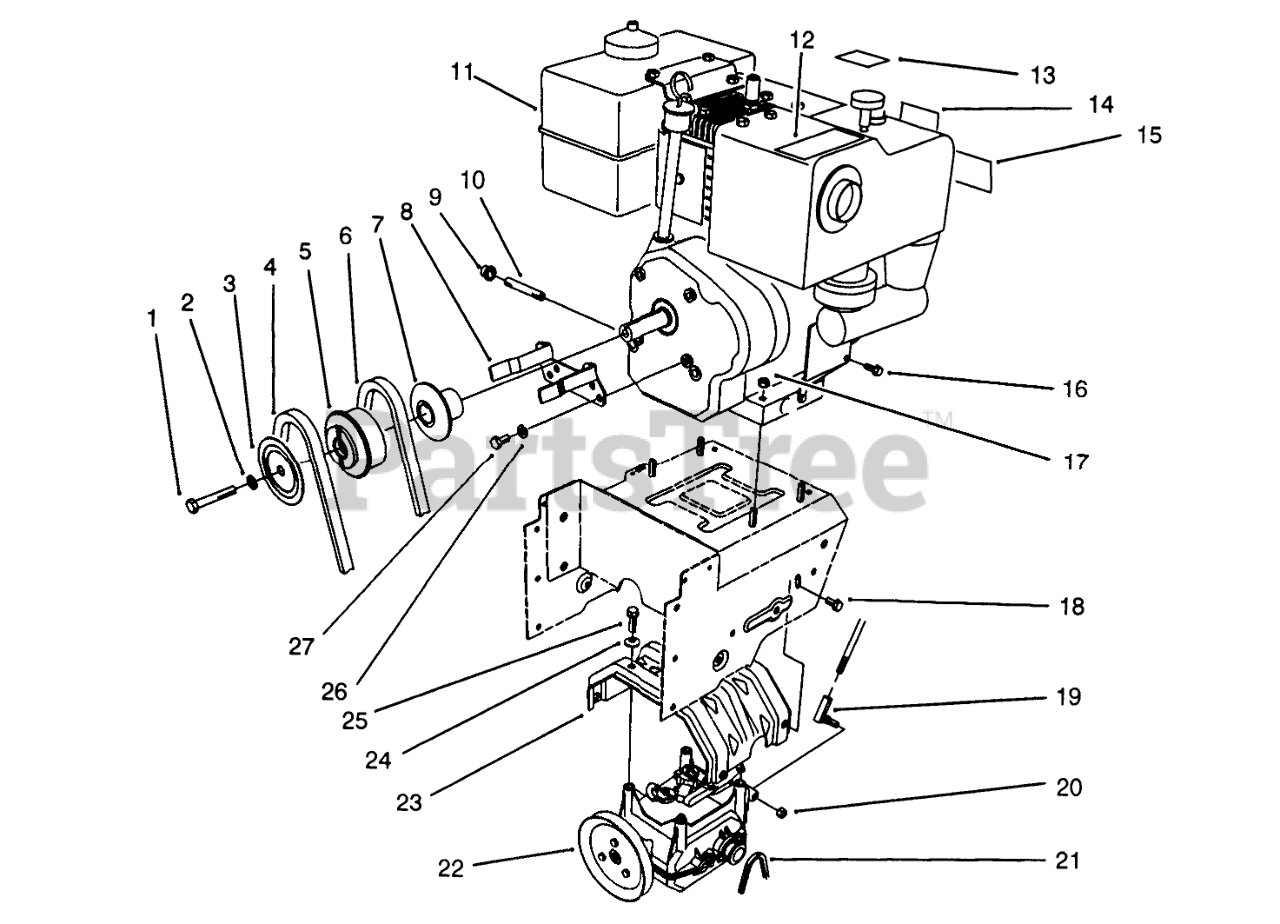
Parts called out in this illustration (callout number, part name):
1	SCREW-HH
2	WASHER-LOCK
3	SHEAVE-HALF, IMPELLER
4	V-BELT, IMPELLER
5	PULLEY-ENGINE, CENTER
6	V-BELT, TRACTION
7	SHEAVE-HALF, TRACTION
8	Guide-Belt
9	CAP-PIPE
10	NIPPLE-PIPE
12	DECAL-WARNING, HOT SURFACE
13	DECAL - THROTTLE, INT'L
14	DECAL - PRIMER, INT'L
15	DECAL - CHOKE
16	SCREW-HH
17	NUT-HF
18	SCREW-HHF
19	JOINT-BALL
20	NUT-LOCK, NI
21	CHAIN
22	TRACTION GEARCASE ASM
23	Frame-Transmission
24	WASHER-SPRING
25	SCREW-HWHTF
26	WASHER-LOCK
27	SCREW-HH
